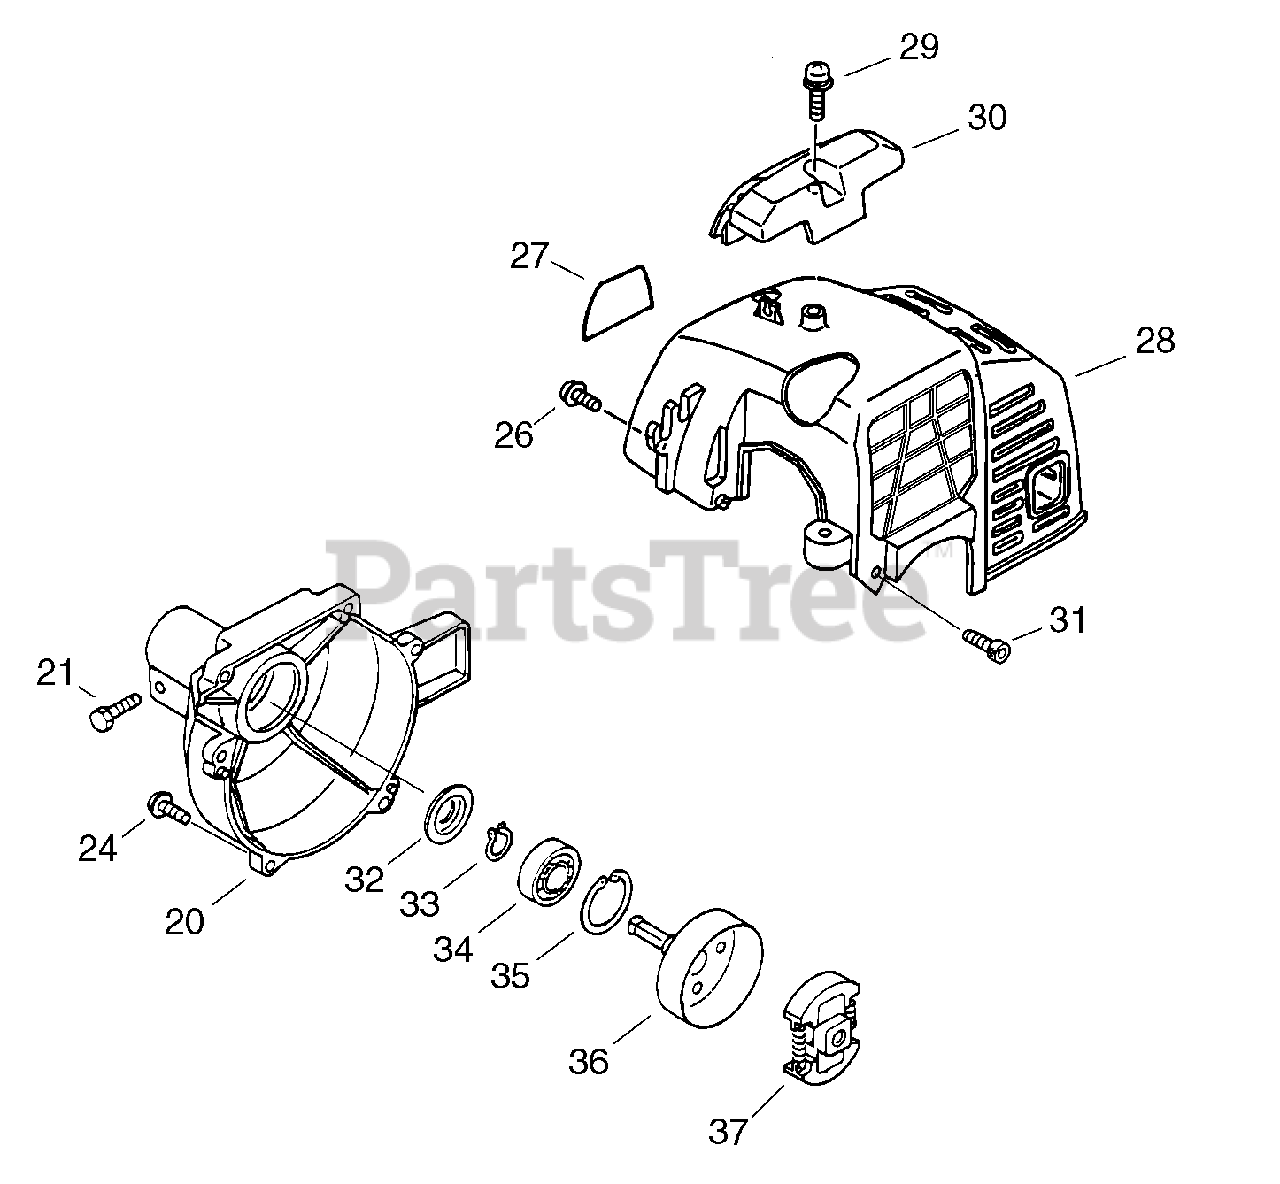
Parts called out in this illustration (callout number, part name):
20	CASE, FAN - ORANGE
21	SCREW - 5X25
24	SCREW - 4X16
26	SCREW - 4X12
27	LABEL - MODEL PPT-2400
28	COVER, ENGINE - ORANGE
29	SCREW - 5X16 -- TAPPING
30	GUARD, TOP - BLACK
31	SCREW - 4X16
32	RETAINER, PIPE
33	RING, RETAINING - 12
34	BEARING, BALL - 6201
35	RING, RETAINING - 32
36	DRUM, CLUTCH
37	CLUTCH ASSY
